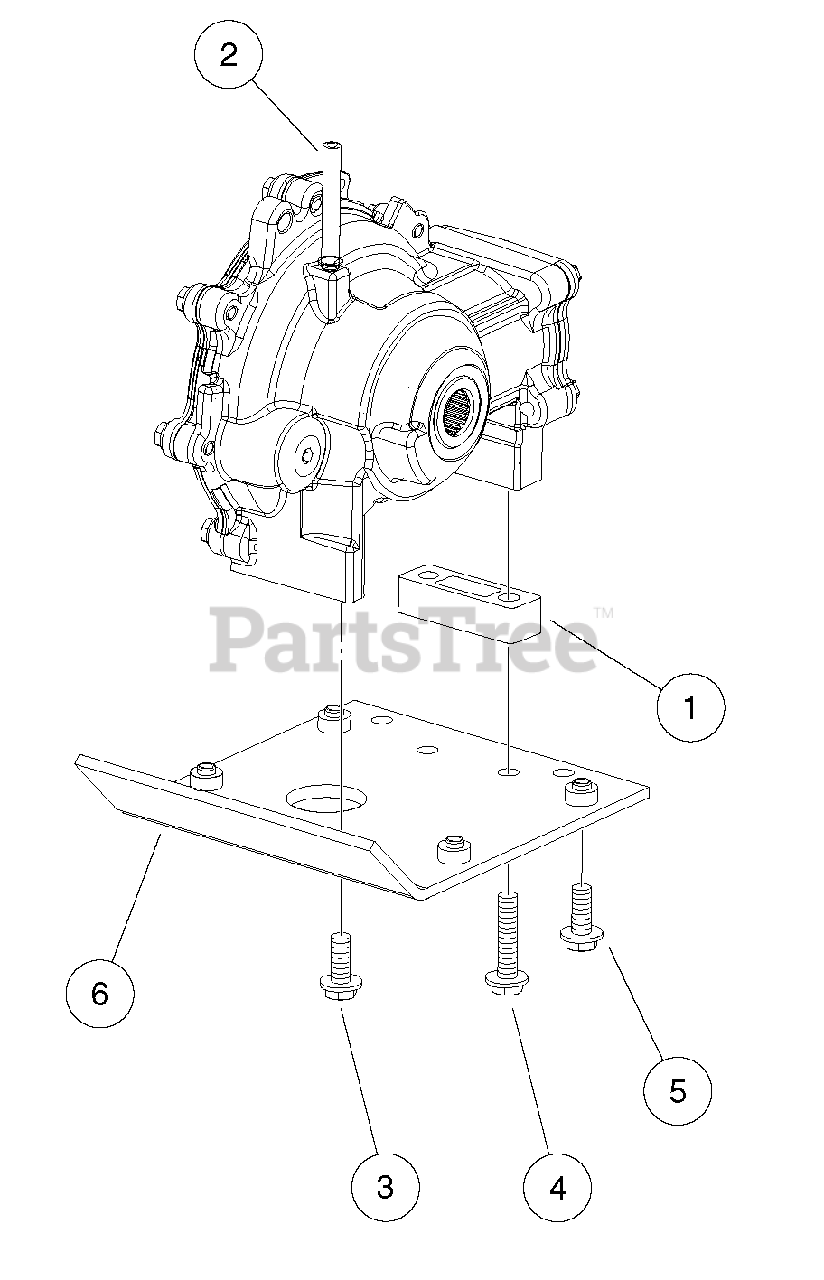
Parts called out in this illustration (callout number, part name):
1	Spacer Block, Diff
2	Hose, Vent, Front Diff
3	Bolt Flanged Head, 3/8-16x1.0 with Loctite
4	Bolt Flanged Head, 3/8-16x1.500 with Loctite
5	Bolt, Flange Head, M10 X 1.5 X 25
6	Asm, Mount, Diff Plate
